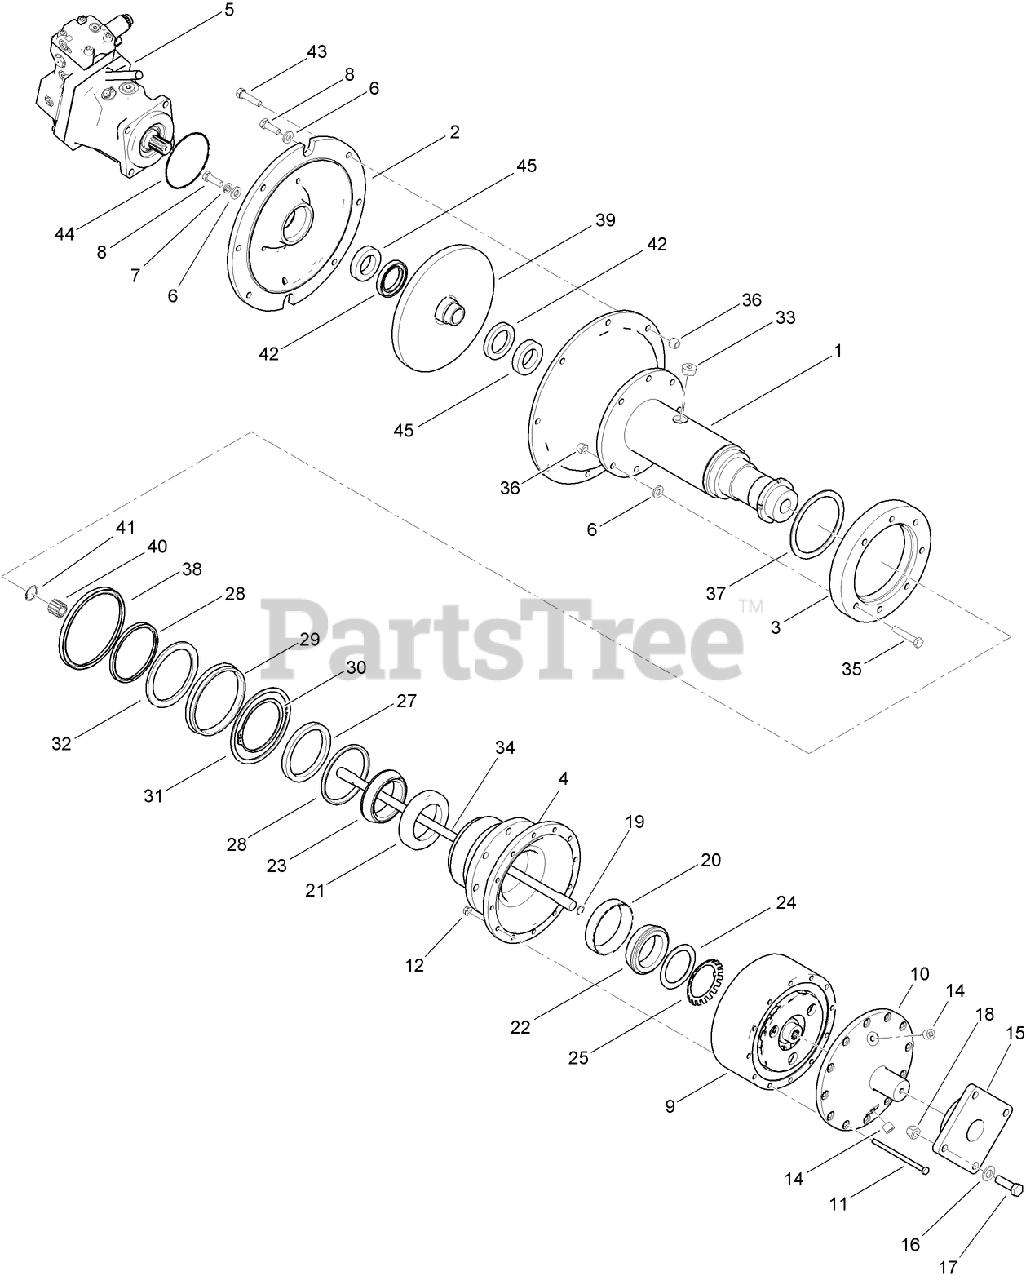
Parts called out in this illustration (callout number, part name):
1	PIVOT-BOOM
2	COVER-FLYWHEEL
3	SPACER-PIVOT, BOOM
4	HUB-SPROCKET
5	HYD MOTOR ASM
7	WASHER-LOCK
8	SCREW-HH
9	GEARBOX ASM
10	COVER-Planetary
12	NUT-FLANGE
14	PLUG-PIPE
15	BEARING
16	WASHER-FLAT
17	SCREW-HH
18	NUT-LOCK, HEX
19	RING-RETAINING, INTERNAL
20	CUP-BEARING
21	BEARING
22	BEARING-CONE
23	BEARING
24	WASHER-Shim
25	WASHER-LOCK, BEARING
28	SEAL-Urethane
29	SEAL-PLANETARY, URETHANE
30	RING-RETAINING, EXTERNAL
31	RING-WEAR
32	WASHER-THRUST, THICK
33	PLUG-FREEZE
34	SHAFT-DRIVE
35	SCREW-HH
36	NUT-HEX
37	WASHER-THRUST, THIN
38	SEAL-URETHANE
39	FLYWHEEL
40	BUSHING-SPLINED
41	RING-RETAINING
42	SEAL-Flywheel
43	SCREW-HH
45	BEARING-Ball
